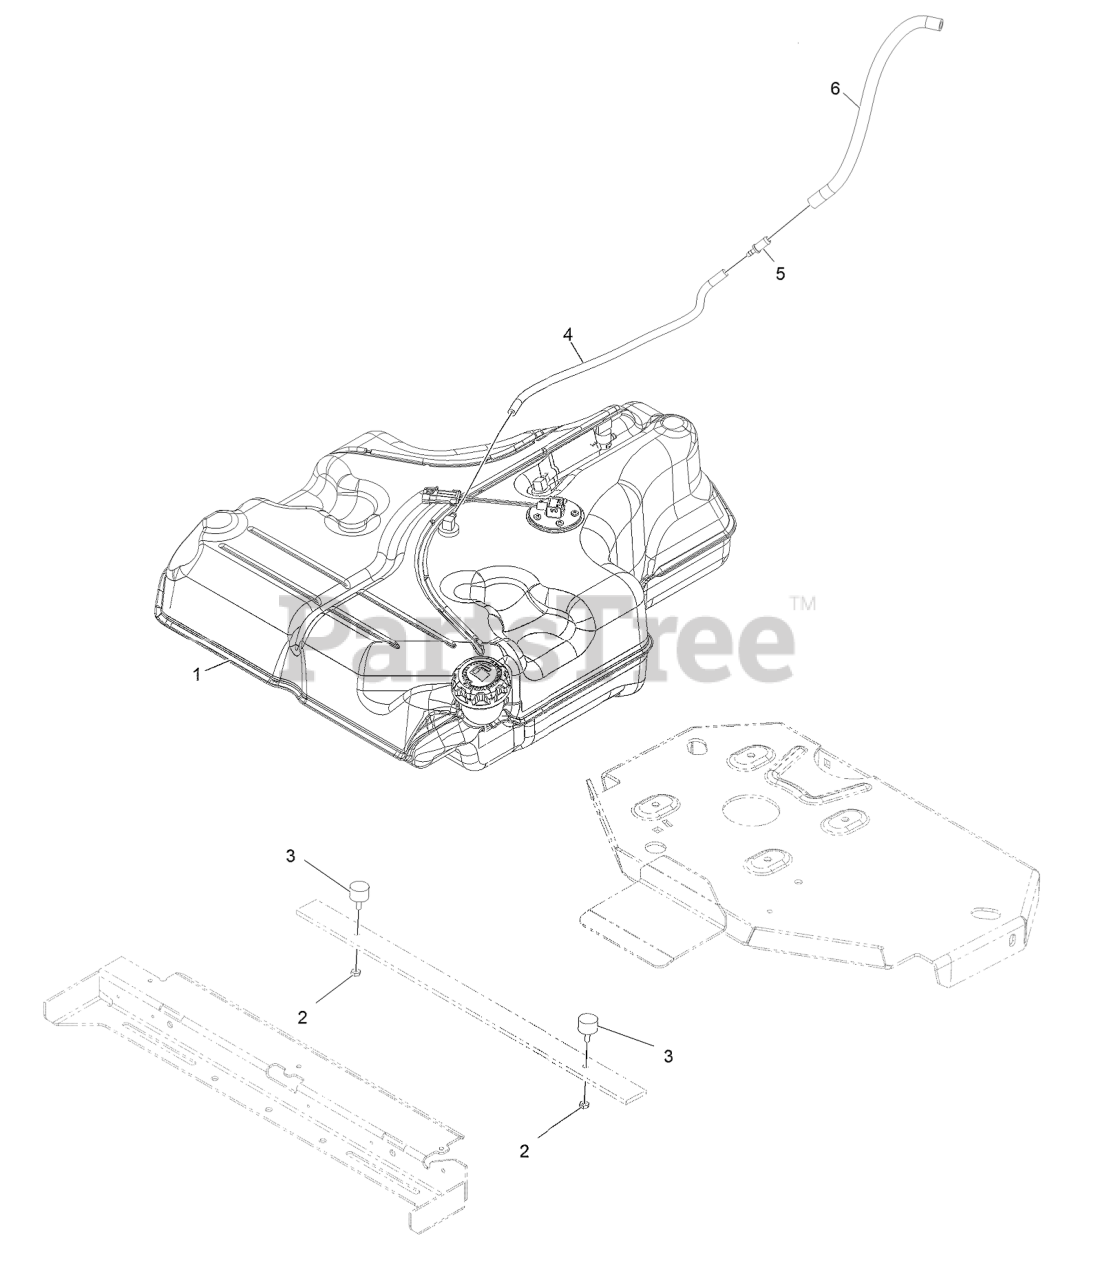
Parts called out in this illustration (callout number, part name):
2	NUT-JAM
4	HOSE-FUEL
5	FITTING-STRAIGHT
6	HOSE-FUEL
